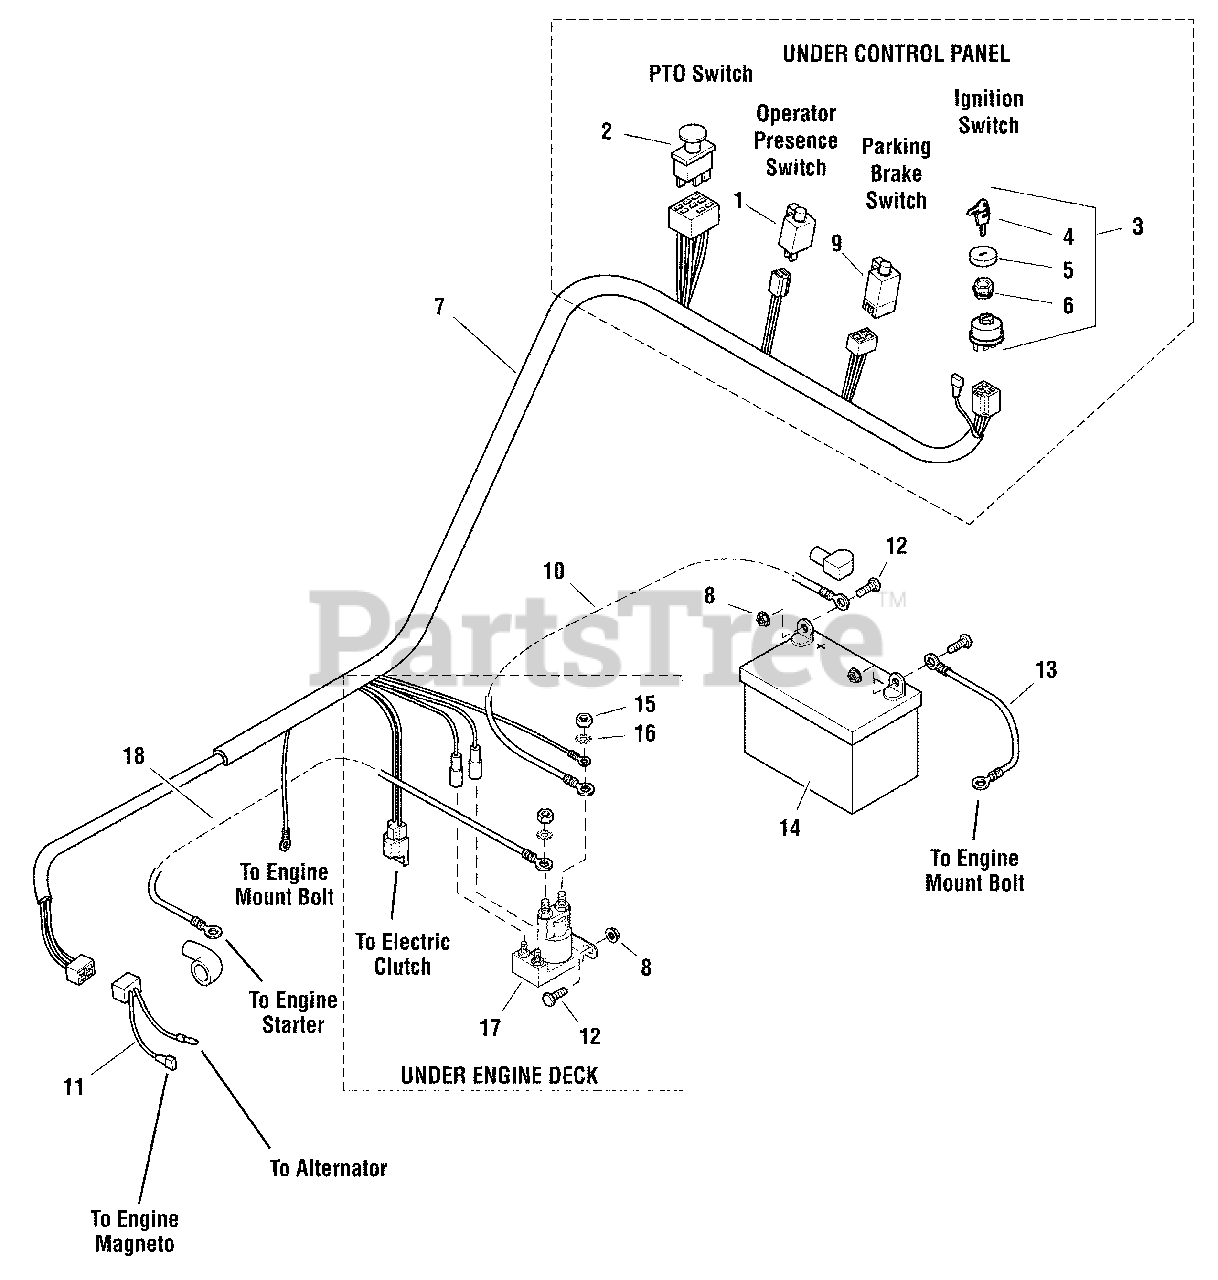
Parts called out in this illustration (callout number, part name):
1	SWITCH, PLUNGER NC
2	SWITCH, BLADE ENGAGEMENT
3	SWITCH, IGNITION, 6 POST
4	KEY, IGNITION MOLDED SET
5	COVER, PLASTIC, SNAP ON
6	PLASTIC NUT
7	WIRE HARNESS, MAIN HYDROCUT/PACER
8	NUT, 1/4-20 HEX SERRATED FLANGE
9	SWITCH, PLUNGER, NO/NO, BOLT-IN
10	BATTERY CABLE, POSITIVE, 22"
11	WIRE HARNESS, HYDROCUT 1732, JUMPER
12	BOLT, 1/4-20 X 3/4
13	BATTERY CABLE, NEGATIVE, 22"
14	BATTERY, WET ( BCIU1, 340 CCA)
15	NUT, HEX JAM 5/16-24
16	WASHER, LIGHT LOCK, 5/16
17	SOLENOID-4 POLE 12 VOLT DC (TROMBETTA)
18	BATTERY CABLE, POSITIVE, 35"
19	GUARD, WIRE - RED
